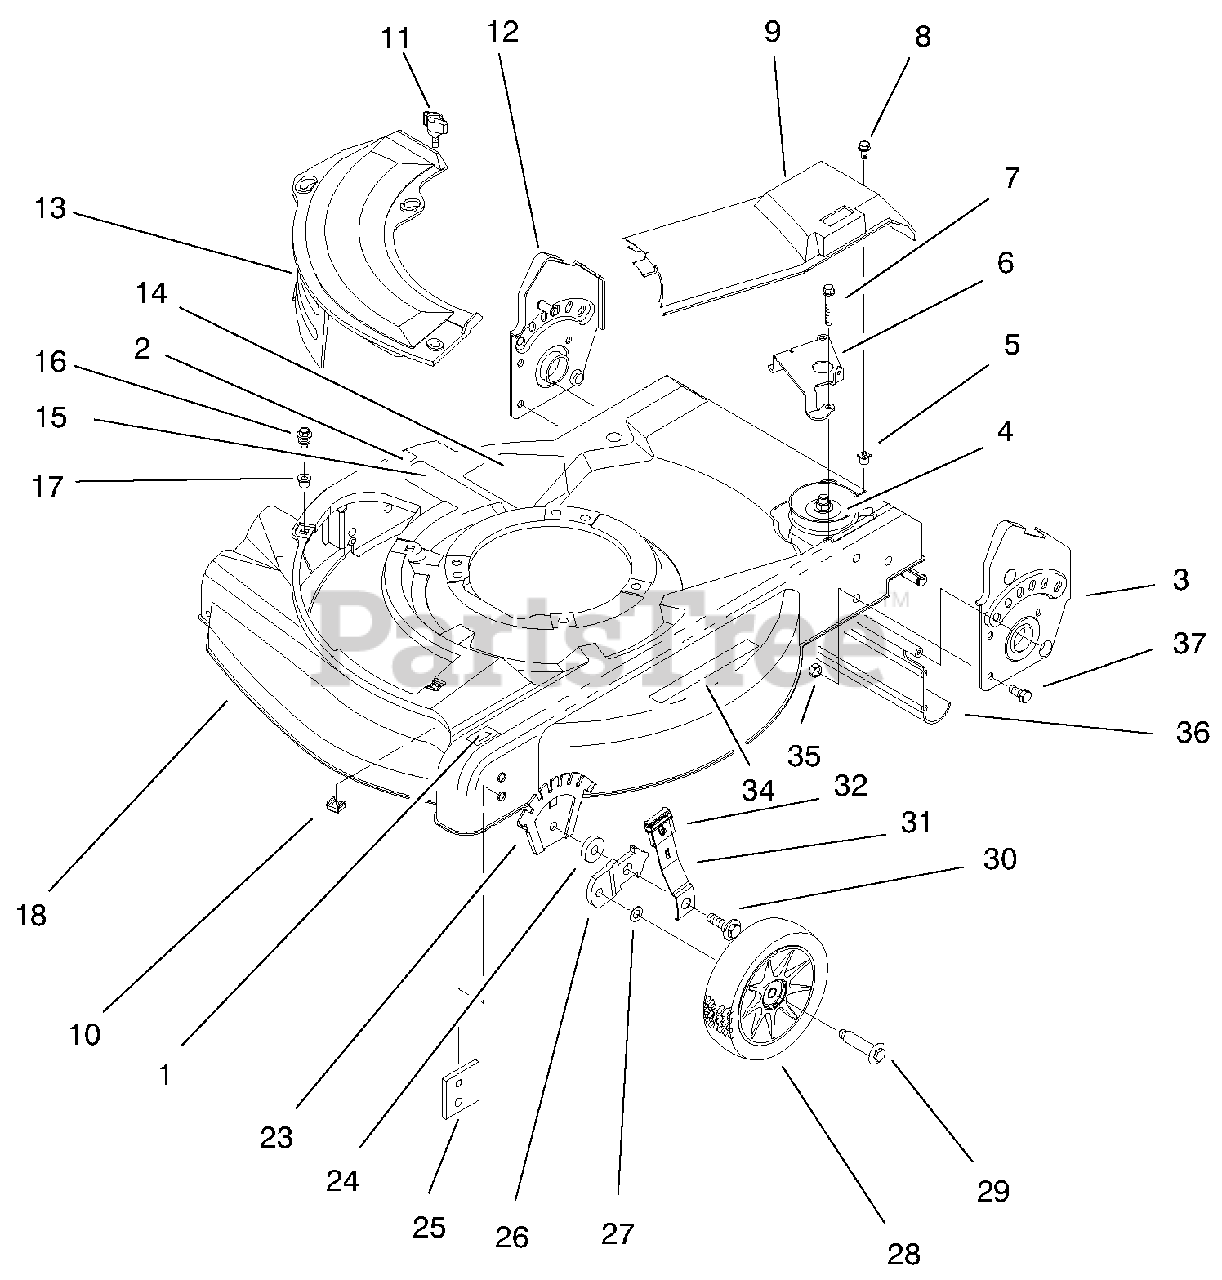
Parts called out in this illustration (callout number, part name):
1	Decal-HOC L
2	Decal-HOC R
3	LH Handle Brkt ASM
4	Assembly-Gear Case
5	Grommet
6	Guide-Transmission
7	Screw-Thread Forming
8	Screw-Pth
9	Cover-Drive
10	Nut-Cage
12	RH Handle Brkt ASM
13	Plate-Mulch
14	Decal-Danger
15	Decal-Warning
16	Screw-Sems
17	Grommet-Plastic
18	ASM-Housing & Baffle
23	Plate-Hght Adj
24	Washer-Wheel
25	Plate-Baffle
26	Bracket-Wheel Ht Adj
27	Washer-Wheel Bolt
28	6" Wheel & Tire ASM
29	Bolt-Shoulder 6" Wheel
30	Bolt-Shoulder
31	Arm-Front Spring
32	Knob-Height Adj Lever
34	Decal-Safety
35	Nut-Lock Ni
36	Shield-Trailing
37	Screw-HH
